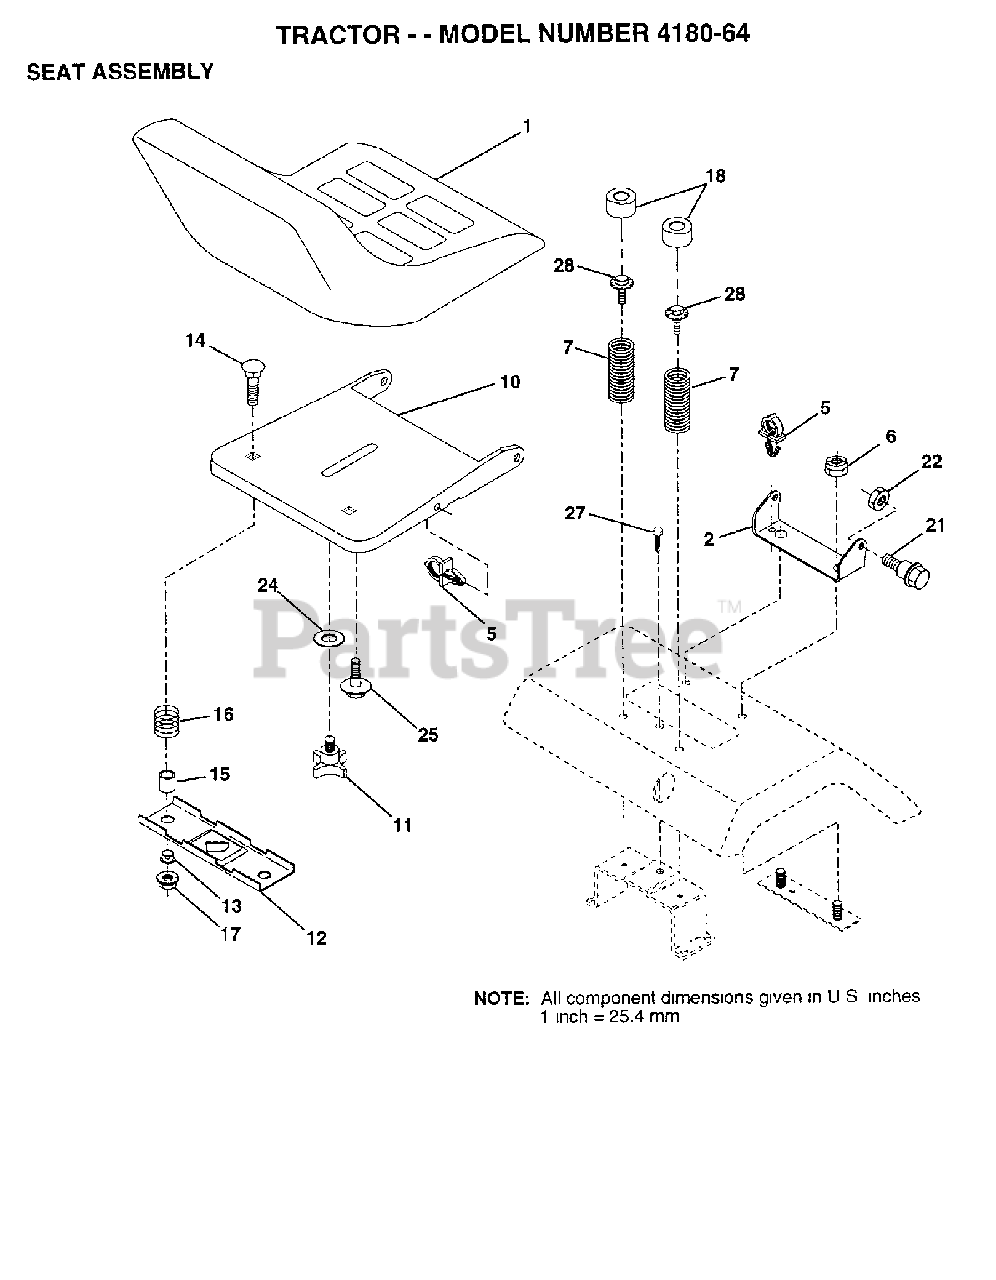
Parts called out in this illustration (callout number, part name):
2	BRKT,SEAT PIVOT**
5	PUSH CLIP
6	NUT
7	SPRING COMPRESSION
10	PAN SEAT
12	BRKT SWITCH
14	BOLT CARRIAGE 1/4-20X1 3/8
15	SPACER SPLIT
16	SPRING COMPRESSED
17	NUT T
18	CAP SPRING
22	LOCKNUT
25	BOLT, SHOULDER**
27	SCREW LT
